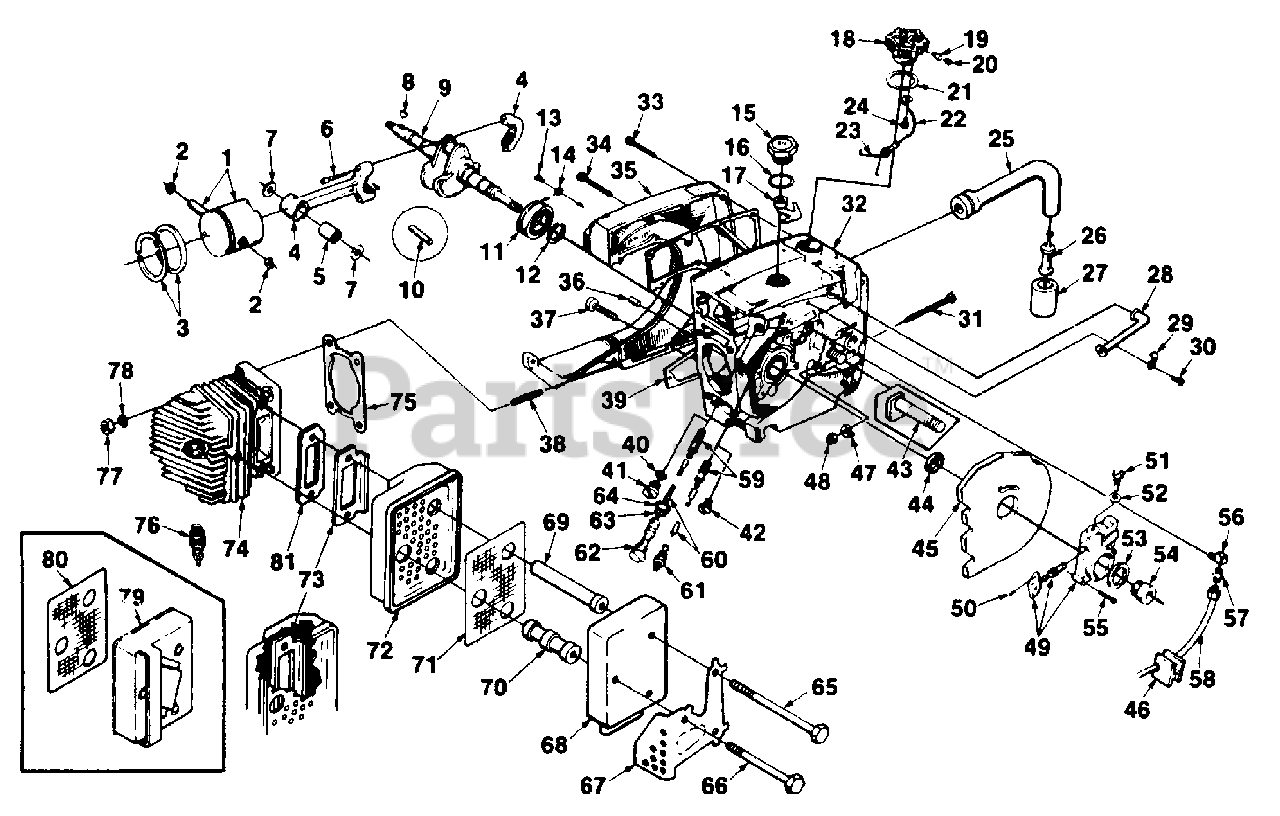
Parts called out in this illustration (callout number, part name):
1	PISTON & PIN
2	RING- Piston pin retaining
3	PISTON RING
4	ROD- Connecting
5	BEARING- Needle
6	SCREW- Soc hd. 8-32 x 9/16
7	WASHER- Thrust
8	KEY- Woodruff
9	CRANKSHAFT
10	BEARING- Needle (set of 28)
11	BEARING- Ball
12	RING- Retaining
13	SCREW- Bearing retaining
14	WASHER- Lock
15	CAP- Oil filler
16	GASKET- Oil cap
17	RETAINER
18	CAP- Fuel filler
19	VALVE- Check (oval duckbill)
20	FILTER- Filler cap
21	GASKET- Fuel cap
22	CHAIN- Bead
23	RETAINER
24	SCREW- Pan hd., plastite 6 x 1/4
25	LINE- Fuel
26	FILTER- Fuel
27	FILTER- Felt
28	CONNECTOR- Fuel line
29	CLAMP- Fuel line
30	SCREW- Pan hd. 6-32 x 5/16
31	SCREW- Guide bar adjusting
32	CRANKCASE
33	SCREW- Fil. hd., 8-32 x 5/8
34	SCREW- Fil. hd., 8-32 x 2 3/16
35	COVER- Fuel tank
36	PIN- Dowel
37	SCREW- Fil. hd. 8-32 x 1 3/4
38	STUD
39	GASKET- Fuel tank
41	CAP- Oil pump
42	PLUG- Pipe
43	BOLT- Guide bar
44	SEAL
45	SHIELD- Sawdust
46	GROMMET- Oil line
47	PIN- Guide bar adjusting
48	NUT- Gripco
49	PUMP- Automatic oil
50	SCREW- Pan hd. 4-40 x 1/4
51	SCREW- Cam
52	GASKET- Cam screw
53	SEAL- Felt
54	WORM- Gear
55	SCREW- Fil hd. 8-32 x 3/4
56	CONNECTOR- Elbow
57	FITTING- Tube
58	LINE- Oil (discharge)
59	FILTER- Oil
60	LINE- Oil pick-up
61	CONNECTOR- Oil filter
62	TUBE- Oil line
63	"O" RING
64	GASKET- Oil line tube
65	SCREW- Hex hd. cap 1/4-20 x 3
66	SCREW- Hex hd. 1/4-20 x 2 3/8
67	SHIELD- muffler
68	CAP- Muffler (SXL-925)
69	SUPPORT- Muffler (long)
70	SUPPORT- Muffler (short)
71	SCREEN- Spark arrestor
72	BODY- Muffler
73	PLATE- Muffler body
74	CYLINDER- 2 1/16" bore
75	GASKET- Cylinder
76	SPARK PLUG CJ-6Y Champion (after Lot #C-246)
76	SPARK PLUG- C-J6 Champion (prior to Lot #C-246)
77	NUT- Hex 1/4-28
78	WASHER- Lock, 1/4
79	KIT- Muffler temperature ("SXL-925W")
80	SPARK ARRESTOR
81	GASKET- Muffler
